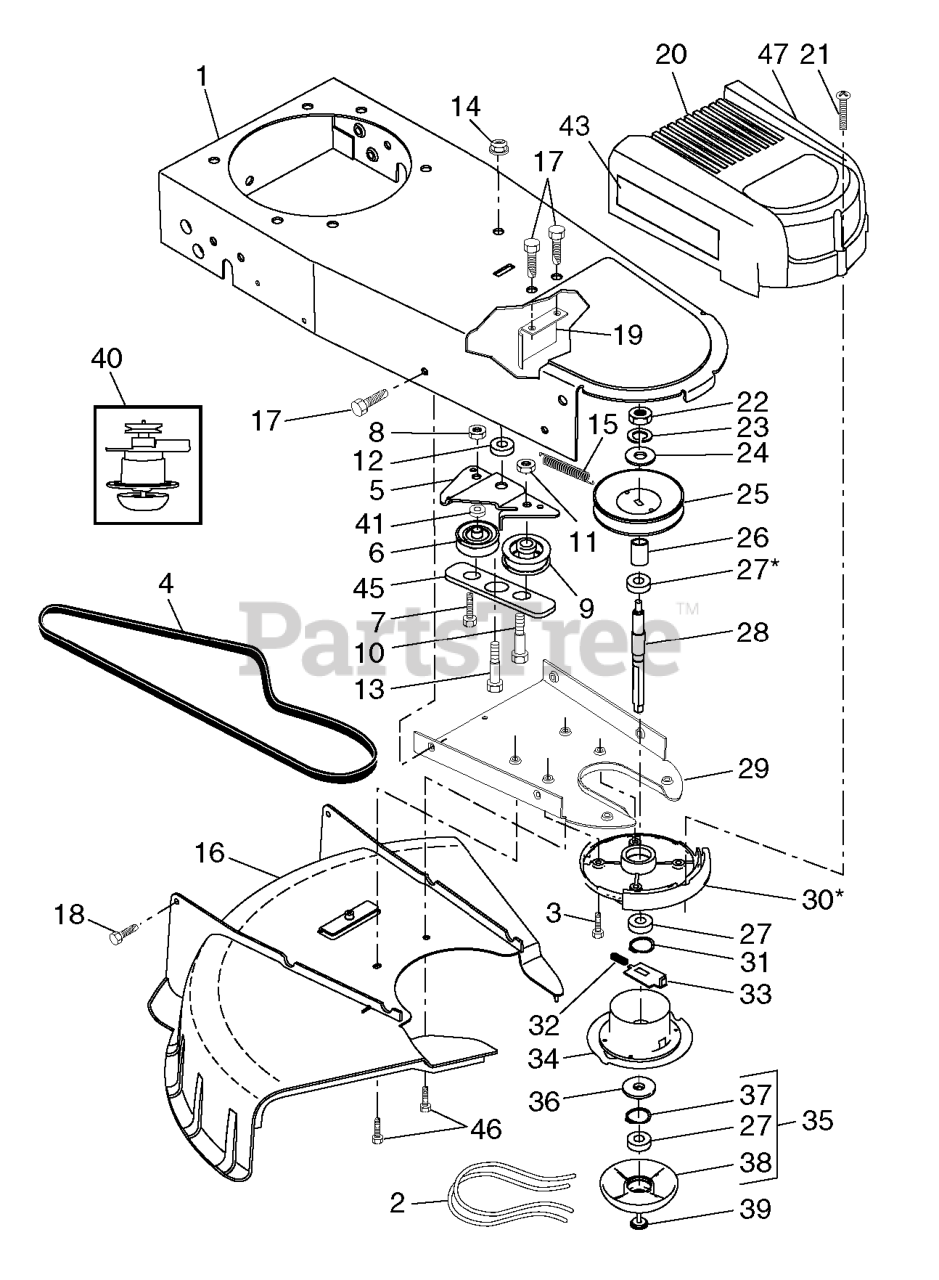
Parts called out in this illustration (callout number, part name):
1	KIT.CHASSIS.ASM.668
2	LINE.BUND.18PC
3	BOLT.HEX.HDWSH.5/16-18X1.00
4	BELT-V.STRING TRIMMER.
5	BRACKET.IDLER.STRG.TRIM.004.15
6	PULLEY.V-GROOVE.IDLER
7	BOLT, HEX HEAD 3/8-16 X 1.25
8	LOCKNUT
9	IDLER PULLEY
10	SHOULDER BOLT
11	NUT.CENTERLOCK.5/16-
12	SPACER.IDLER.BRACKET
13	BOLT SHOULDER 3/8 -16X1
14	NUT.HEX.FLANGE.3/8-16.LOCKNUT
15	SPRING.RETURN.WHEELED.TRIMMER
16	DEFLECTOR.BOTTOM.HW.TRIMMER
17	SCREW 14-20 X 5/8
19	KEEPER.BELT.STRING.TRIM.BZP.15
20	COVER.SUBASM.COVER/IMD.HUSQ
21	SCREW.SLOT.TORX.
22	NUT
23	LOCKWASHER
24	WASHER, FLAT 3/8
25	PULLEY.SPINDLE.WHEELED.TRIMMER
26	SPACER, PULLEY
27	BEARING
28	JACKSHAFT.WHEELED.TRIMMER
29	CHASSIS.COVER.BOTTOM.BLACK
30	SPINDLE HOUSING ASSEMBLY
31	RING, RETAINING, EXTERNAL,
32	SPRING.1.5".COMPRESSION
33	PLATE.LOCKING.WHEELED.TRIMMER
34	CARRIER PLATE ASSEMBLY
35	MOW BALL ASSEMBLY
36	COVER, BEARING
37	RING, RETAINING, INTERNAL,
38	MOW BALL
39	BOLT, MOW BALL
40	ASM.ADJUSTABLE.SPINDLE.WHLD.TR
41	SPACER (2 2MC)
43	DECAL.TRIMMER.WHEELED.INSTRUCT
45	BRACKET.BELT.KEEPER.BLACK
47	DECAL.TRIMMER.WHEELED.HEIGHT
